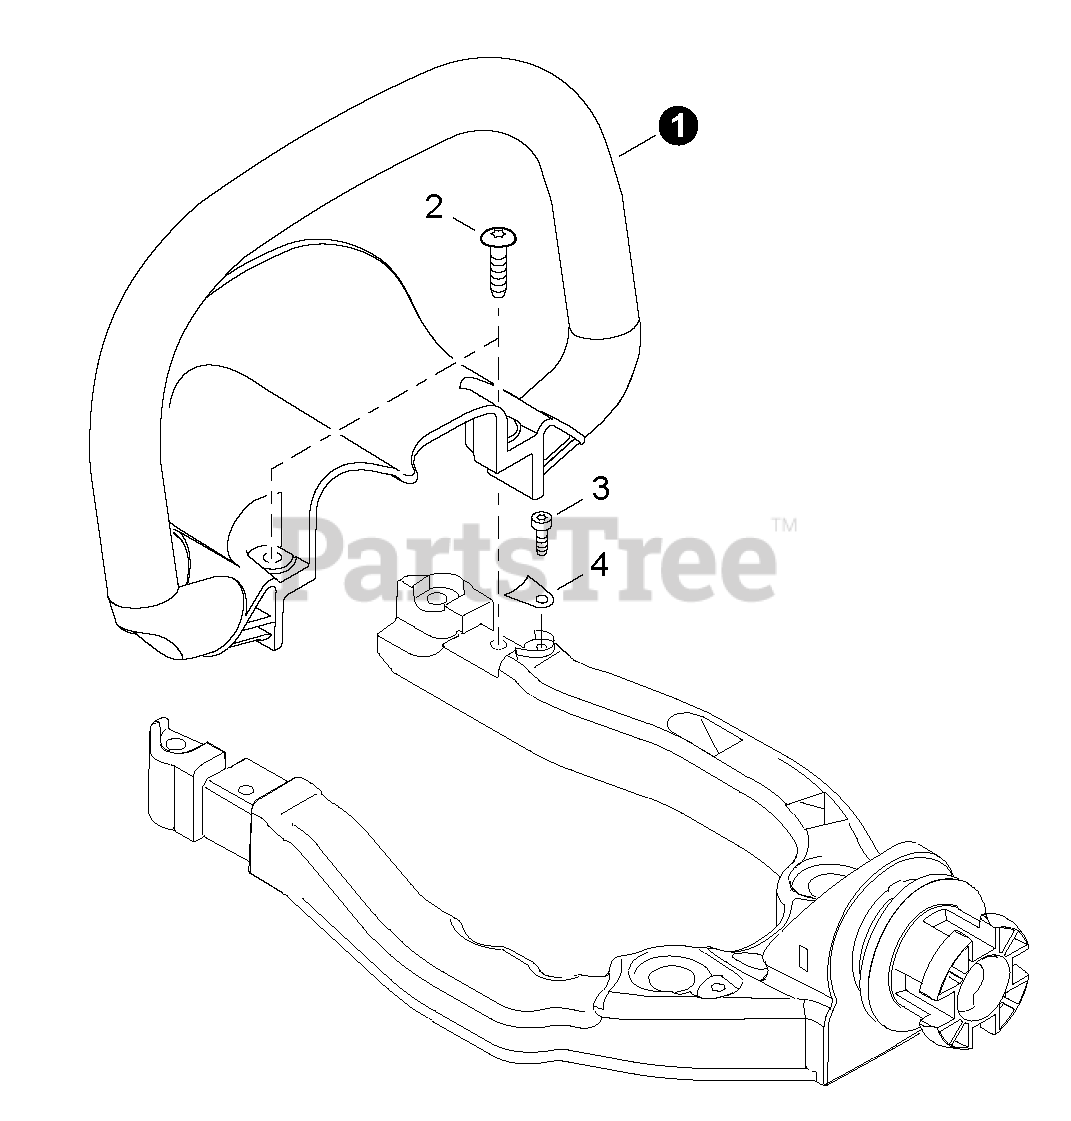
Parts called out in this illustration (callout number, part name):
1	HANDLE - FRONT
2	SCREW - 6
3	SCREW - 4X12
4	RETAINER, BRAKE BAND
